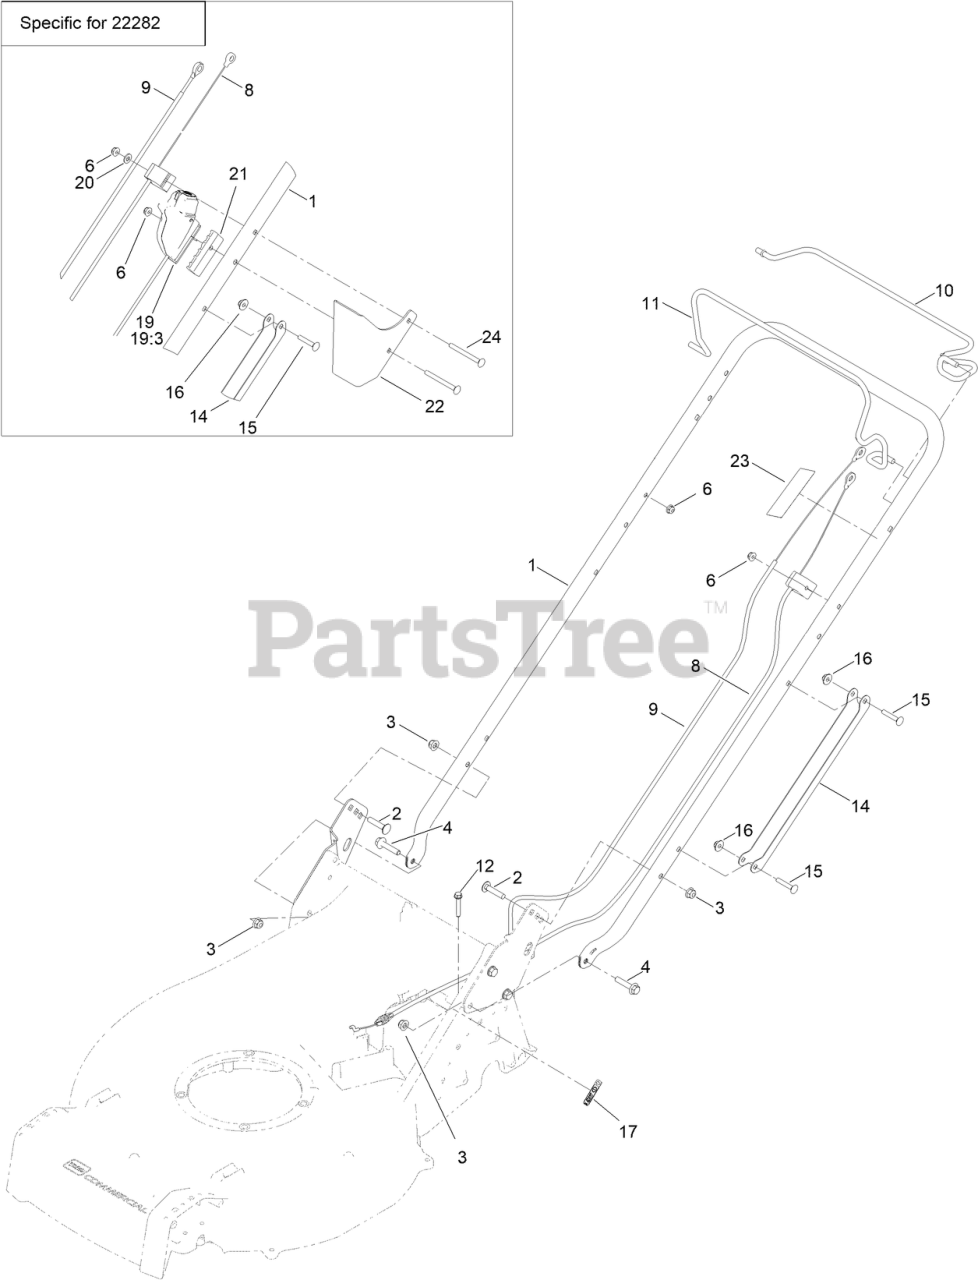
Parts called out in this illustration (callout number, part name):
2	BOLT-CARR
3	NUT-HF, NI
4	SCREW-HHF
6	NUT-HF
8	CABLE-BRAKE, 60V
9	CABLE-TRACTION
10	BAIL-TRACTION
11	BAIL-BRAKE
12	SCREW-HWH
14	GUARD-CABLE, HANDLE
15	SCREW-CARR
16	NUT-HF
19	STARTER SWITCH ASM
19:3	STARTER BUTTON SERVICE ASM
20	WASHER-FLAT
21	SPACER-HOUSING, SWITCH
22	GUARD-HOUSING, SWITCH
23	DECAL-CONTROLS (60V START)
24	SCREW-CARR
